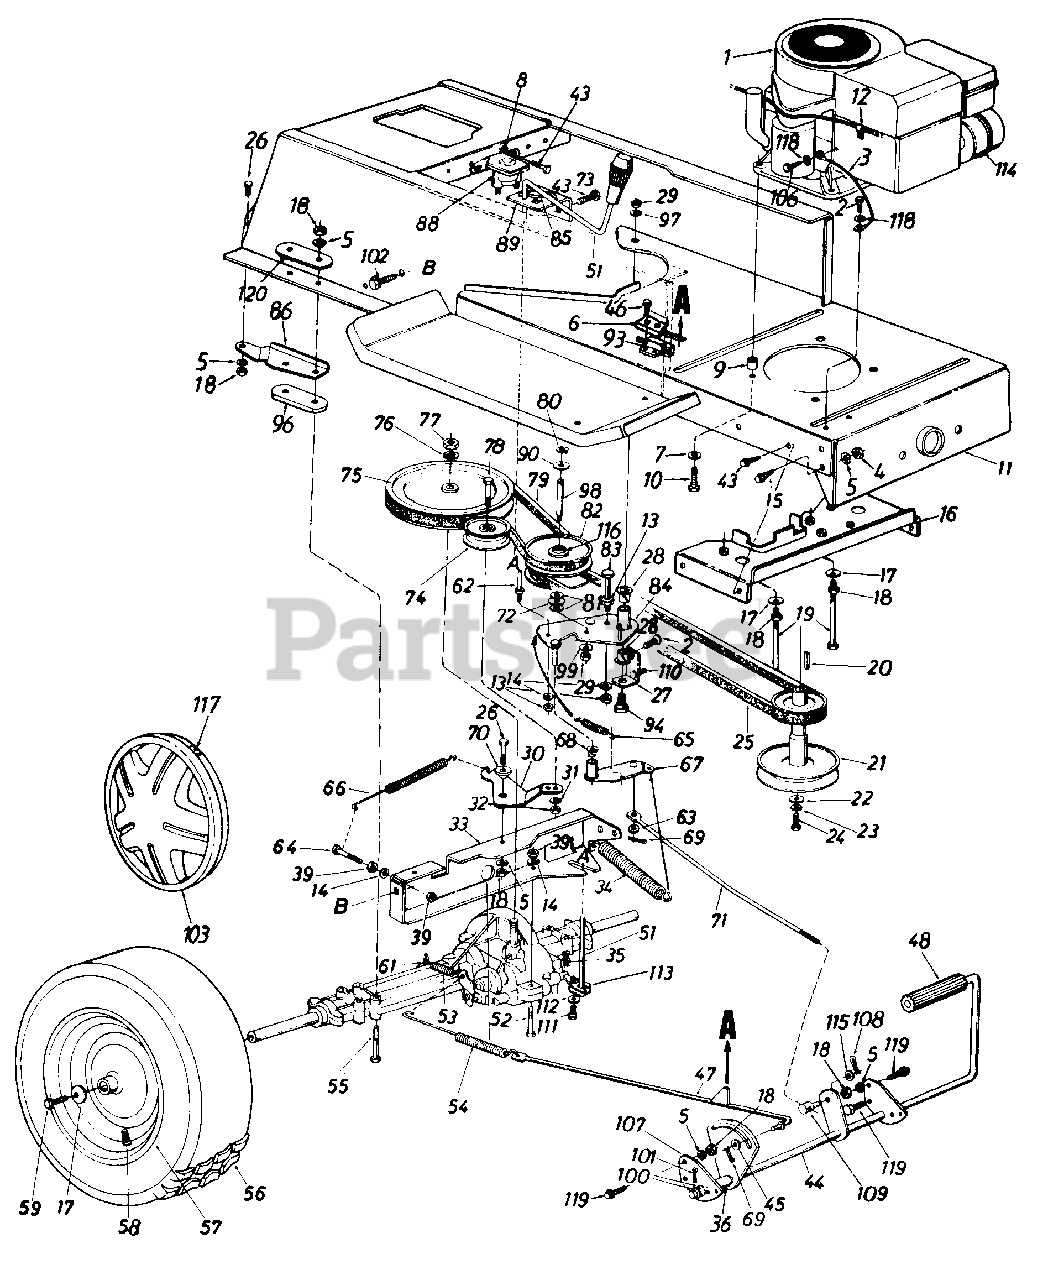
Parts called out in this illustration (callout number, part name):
1	Engine
2	Hex Wash. AB-Tap Scr. 5/16" x .75"
3	Electric Ground Wire
4	Hex Nut 5/16-24 Thd.
5	L-Wash. 5/16" I.D.
6	Switch Plate
7	Fl-Wash. .406" I.D. x 1.25"
8	Ext. L-Wash. 1/4" I.D.
9	Spacer
10	Hex L-Wash. Tap Scr. 3/8-16 x 1.5 Lg.
11	Lower Frame Ass'y.
12	Speed Clip
13	Hex Nut 1/4-20 Thd.
14	L-Wash. 1/4" I.D.
15	Rib Neck Bolt 5/16-24 x .84" Lg
16	Belt Guard Brkt. Ass'y.
17	Bell-Wash. .345" I.D. x .88"
18	Hex Nut 5/16-18 Thd.
19	Hex Bolt 5/16-18 x 4.0"
20	Sq. Key 1/4" x 1/4" x 2.00"
21	Engine Pulley
22	Fl-Wash. 7/16" I.D. x 1.25"
23	L-Wash. 7/16" I.D.
24	Hex Bolt 7/16-20 x 1.50" Lg.
25	Variable-Speed Belt
26	Hex Bolt 5/16-18 x .75" Lg.
27	Bearing Shaft Bracket Ass'y.
28	Flanged Nyliner Brg. 5/8" I.D. x .88" Lg.
29	Hex Nut 3/8-24 Thd.
31	L-Wash. 3/8" I.D.
32	Hex Nut 3/8-24 Thd.
33	Transaxle Support Brkt.
34	Ext. Spring .94" O.D. x 7.58"
35	Inter. Cott-Pin
36	Spacer.63" I.D.
39	Hex Nut 1/4-28 Thd.
43	Hex Wash. Hd. S-Tap Scr. 1/4-20 x .50" Lg.
44	Clutch/Brake Pedal Ass'y.
45	Fl-Wash.
46	Truss Mach. Scr. B-Tap Scr. #10 x .5" Lg.
47	Brake Rod Ass'y.
48	Foot Pad
51	Shift Lever Ass'y.
52	Hex Bolt 1/4-28 x 1 .75" Lg.
53	Ext. Spring .38" O.D. x 2.5"
54	Ext. Spring 7.08"
55	Hex Bolt 5/16-18 x 3.75" Lg.
57	Wheel Rim Only
58	Air Valve
59	Hex Bolt 5/16-24 x .75" Lg.
61	Brake Return Spring Anchor
62	Belt Guard Pin 1/4-20 Thd.
63	Fl-Wash. .34" I.D. x .68" O.D.
64	Hex Bolt 1/4-28 x 1.25" Lg.
65	Ext. Spring
66	Ext. Spring .62" O.D. x 6.12
68	Flanged Bearing
69	Cotter Pin 3/32" Dia.
70	Shoulder Spacer .27" Lg.
71	Speed Control Link
72	Truss Bearing .56 Dia. x 1 .25"
73	Shift Knob
74	Fl-Idler Pulley 3.25" x .75n
75	"V"-Pulley
76	L-Wash. 1/2" I.D.
77	Hex Jam Nut 1/2-20 Thd.
78	Hex Bolt 3/8-24 x 1.75" Lg.
79	Variable Speed Belt
80	Snap Ring .56" Dia.
81	Fl-Wash.
82	Variable Speed Pulley Ass'y. 5" O.D.
83	Hex Bolt 1/4-20 x 3.25" Lg.
90	Teflon Washer .565" I.D.
93	Safety Switch
94	Shld. Bolt 3/8-24 x 3.12" Lg.
96	Transaxle Spacer
97	Bell-Wash. .38" I.D. x .88"
98	Shaft .56" Dia. x 3.875" Lg.
99	Bell-Wash. .39" I.D. x 1.12"
100	Fl-Wash. .64" I.D. x .94"
101	Cotter Pin 1/8" Dia. x 1.25"
102	Hex Wash. Hd. Scr. 5/16-18 x.62" Lg.
103	Hub Cap
109	Ferrule
110	Hex Bolt 5/16-18 x 1.0" Lg.- (Grade 5)
111	Hex Bolt 1/4-28 x .50" Lg.
112	Bell-Wash. .265" I.D. x .75"
113	Shift Lever Link Ass'y.
114	Muffler
115	Fl-Wash. .385" I.D. x .62"
116	Needle Brgs.
117	Spring Clip
118	External L-Wash. 5/16" I.D.
119	Hex Wash. TT-Tap Scr. 5/16-18 x .75"
